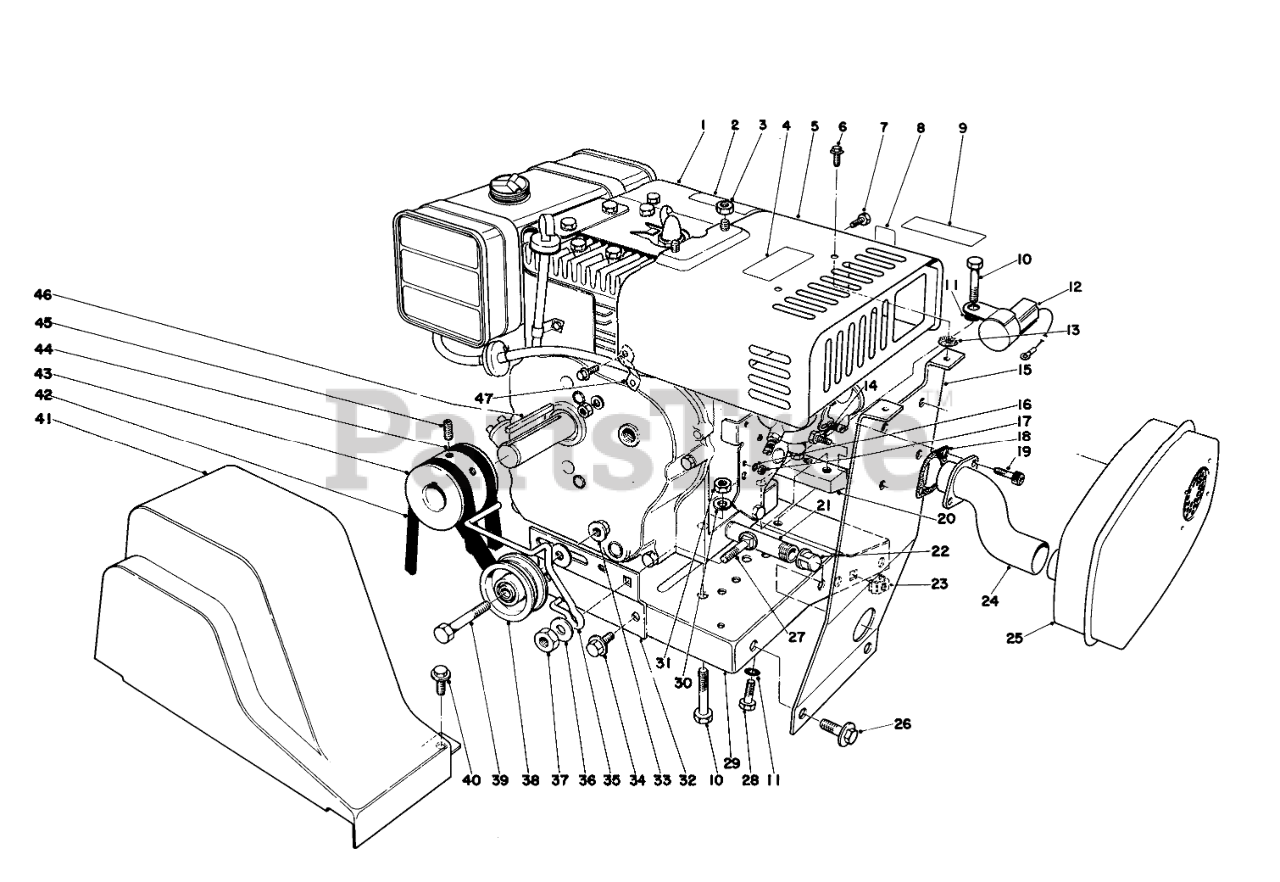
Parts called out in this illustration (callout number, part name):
1	Engine
2	Decal-Hazard
3	NUT-HEX, SIDE DEFORM
4	Decal Hot Surface Warning
5	Heater Box
6	SCREW
8	CHOKE DECAL
9	DECAL SYNCHRO BALANCE
10	SCREW-HH
11	WASHER-LOCK, INTERNAL
12	INTERLOCK MODULE
13	Washer
14	1/4-20 X 1/2 SEMS MS
15	Muffler Mounting Bracket
16	WASHER-LOCK/INT
17	NUT-LOCK
18	Gasket
19	SCREW-HSH
20	Block Engine Mounting
21	NIPPLE-PIPE
22	CAP-PIPE
23	Retained Nut
24	EXHAUST PIPE
25	Muffler
26	SCREW-HH
27	SCREW-CARR
28	SCREW-HH
29	Base-Engine
30	WASHER-PLAIN
31	NUT-LOCK, NI
32	BELT IDLER BRKT
33	NUT-HHF, WHIZ
34	SCREW-HHFTF
35	BELT GUIDE
36	WASHER-FLAT
37	NUT-HEX
38	PULLEY B
39	SCREW-HH
40	SCREW-HWH
41	BELT GUARD
42	V-BELT
43	ENGINE PULLEY
44	V-BELT
45	Screw-Set
47	Brace Heater Box
